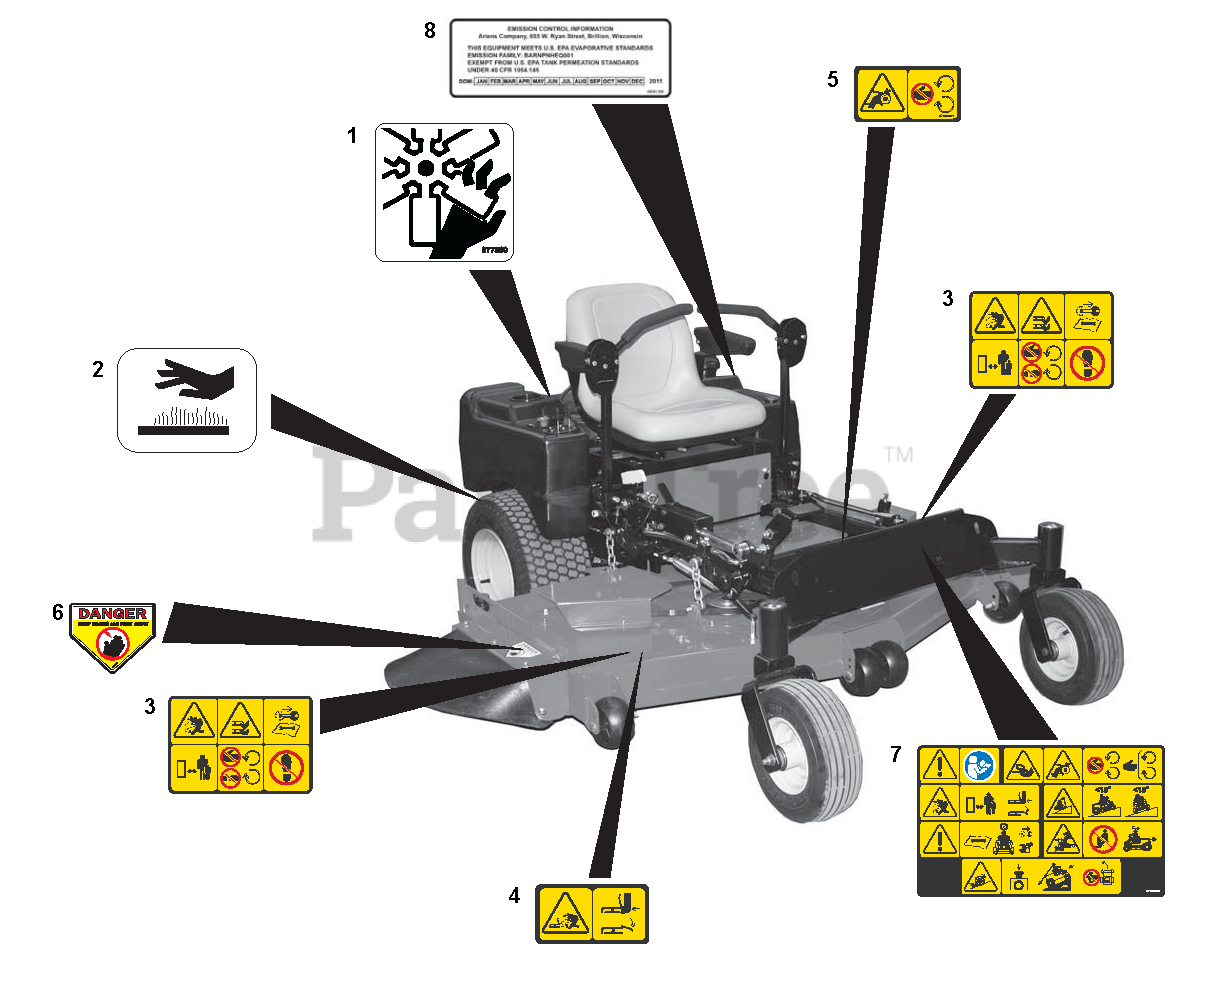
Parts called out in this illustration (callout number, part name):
1	DECAL, DANGER FAN
2	DECAL, HOT SURFACE
3	DECAL, SAFETY - MOWER DECK
4	DECAL, SAFETY - DECK GUARDING
5	DECAL, SAFETY - GUARDING
6	DECAL, DANGER
7	DECAL, MAIN SAFETY
8	LABEL, EPA NON-COMPLIANT TANK
